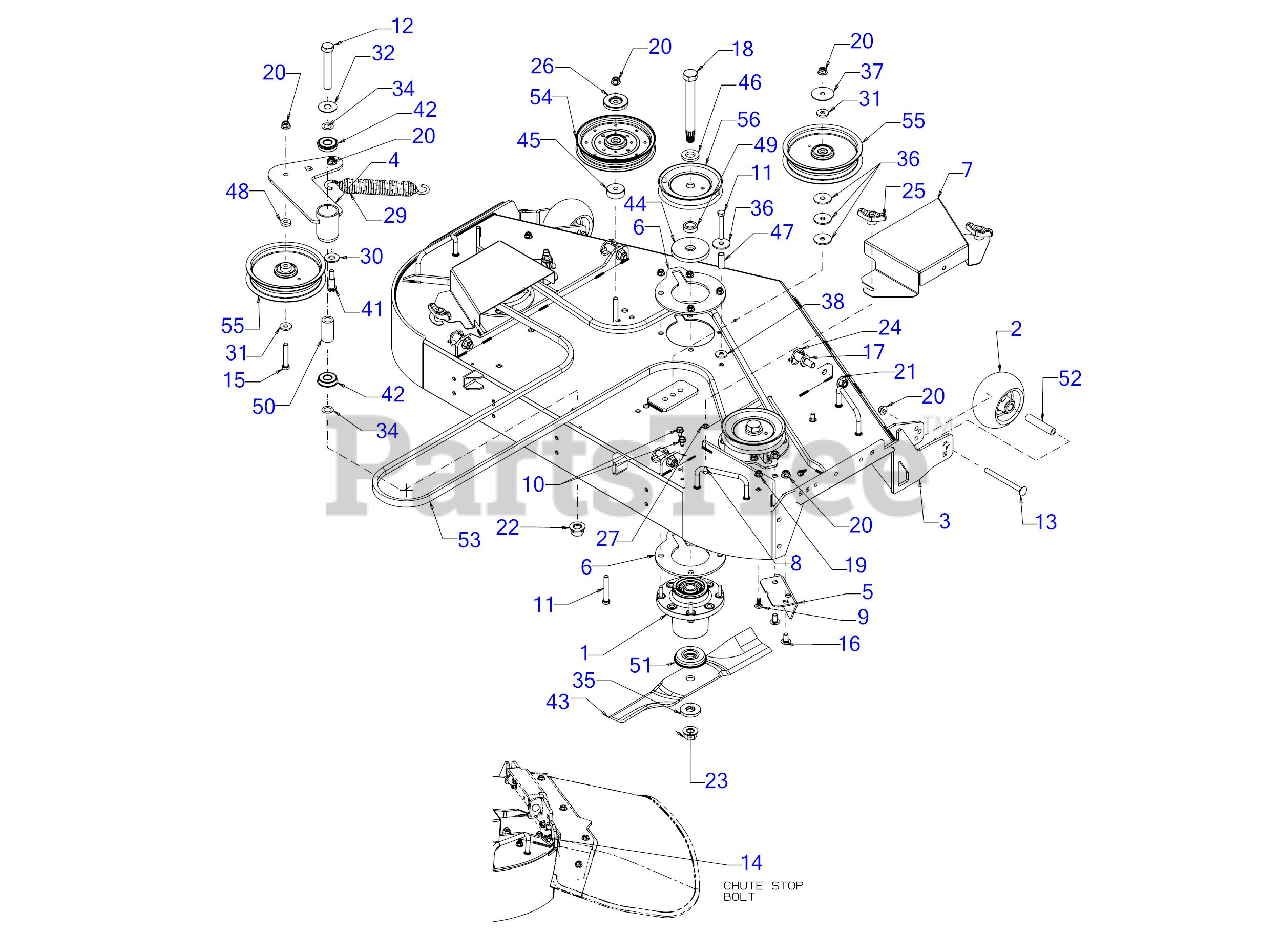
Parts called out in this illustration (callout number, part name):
1	SPINDLE ASSEMBLY
2	5" DIA DECK WHEEL COMPLETE
3	48" FAB DECK ASSEMBLY
4	IDLER ARM ASSEMBLY
8	CARRIAGE BOLT 5/16-18 x 1.00
9	CARRIAGE BOLT 5/16-18 x .75
10	SCREW 5/16-18 x .500
11	HEX SCREW-3/8-16X2.5 GR5
12	SCREW 5/8-18 x 4 GR5
13	CARRIAGE BOLT 3/8-16 x 4.25 GR5
14	SCREW 1/4-20X.625
15	SCREW 3/8-16 x 2.25 GR5
16	CARRIAGE BOLT 3/8-16 x .75
18	SPINDLE SHAFT
19	FLANGE LOCK NUT 5/16-18
23	FLANGE NUT - 5/8-18 GDE 8
25	WING KNOB 5/16-18
26	PULLEY CAP
28	DECK SKID PLATE (LH)
29	SPRING 1.25" DIA X 8.5" LONG
30	FLAT WASHER
31	FLAT WASHER .385 x 1.00 x .135
32	FLAT WASHER-.63IDX1.595ODX.62
33	FLAT WASHER
34	FLAT WASHER
35	FLAT WASHER - SPECIAL
36	FLAT WASHER .406X1.500X.105
37	HUB CAP WASHER .406 x 1.92 x .060
38	FLAT WASHER .406ID X1.0 OD
40	SHOULDER SCREW .43X.29X5/16-18 TT
41	SHOULDER SCREW .50X.925
42	BALL BEARING
43	17" BLADE (HI LIFT)
43	Cub Cadet 48" HI LIFT BLADE SET
43	17" HI-LIFT BLADE 0.756 ID
43	LOW-LIFT 17" BLADE (48"DECK)
43	BLADE-HI LIFT 17.0
43	17" BLADE (MULCH)
44	DECK SPINDLE SPACER
45	SPACER - .385 ID x 1.500DX .585 L
46	SPACER .812 ID x .218 LG
49	SPACER (.792 X 1.20 X .380)
50	SPACER 0.63 X 1.00 X 2.01
51	SPACER 0.790 X 2.75 X 0.486
52	WHEEL SPACER .38ID x 3.04LG
53	DECK BELT - B SEC x 143.25
54	IDLER PULLEY
55	IDLER PULLEY (6.00" DIA)
56	DECK SPINDLE PULLEY (5.39 DIA)
